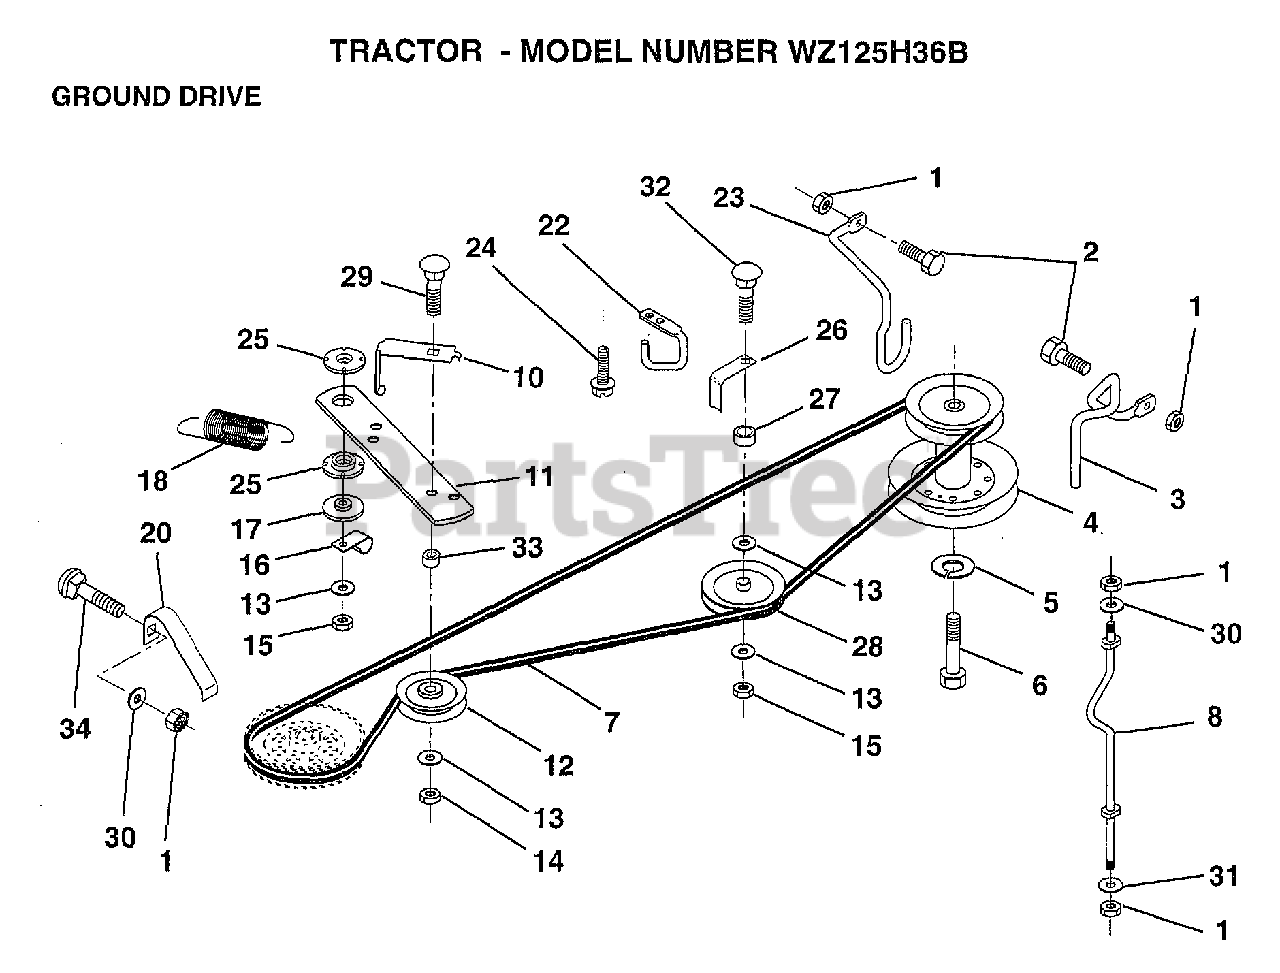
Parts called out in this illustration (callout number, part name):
1	NUT
2	BOLT
3	KEEPER.BELT.FRT.
4	PULLEY.ENGINE.LR
5	LOCKWASHER
6	HEX BOLT
7	BELT-V.DRV.77.75
8	KEEPER.BELT.HYDRO
10	KEEPER.BELT.GRD.
11	ARM-IDLER.DR.GRND
12	PULLEY.IDLER.FLAT
13	WASHER
14	LOCKNUT
16	"CLIP,INSULATOR"
17	SPACER
20	KEEPER.BELT.LH
22	"KEEPER,FRA DR BEL"
23	KEEPER MOWER LH
24	SCREW
25	BUSHING.NYLON
26	KEEPER.BELT.IDLER
27	SPACER.625X.843
28	PULLEY.IDLER.V.GR
29	BOLT RDHD 3/8-16
30	WASHER
31	WASHER M
32	BOLT
34	BOLT
